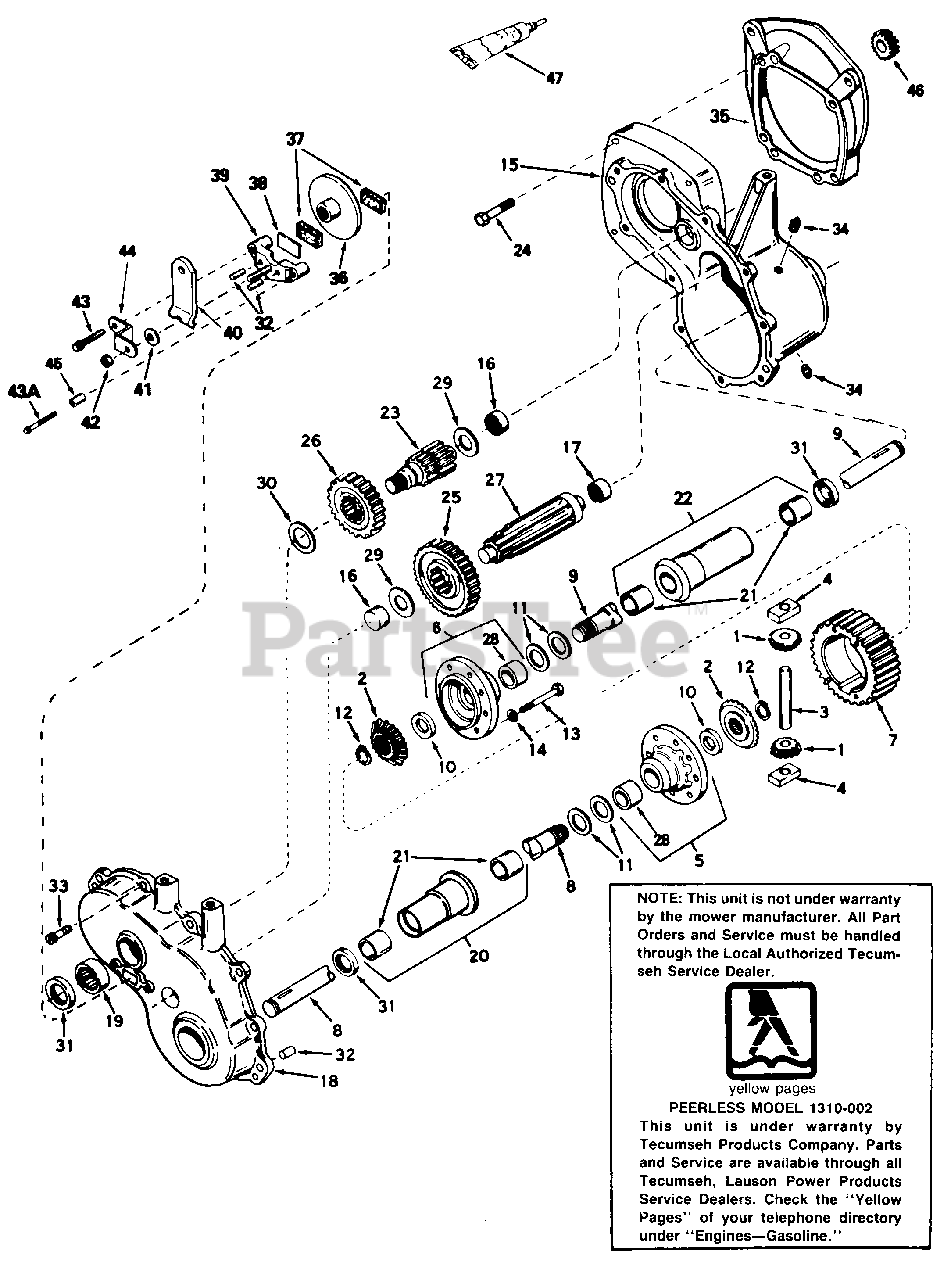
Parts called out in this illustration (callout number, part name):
1	Pinion: Bevel
2	Gear: Bevel
3	Pin: Drive
4	Block: Drive
5	Carrier Ass'y.: Differential
6	Carrier Ass'y.: Differential
7	Gear: Ring
8	Axle
9	Axle
10	Washer
11	Washer: Thrust
12	Ring: Snap
13	Screw: Hex Hd.: 1/4-20 x 21/4
14	Lock Washer: 1/4"
15	Case Ass'y.
16	Bearing: Needle
17	Bearing: Needle
18	Cover Ass'y.
19	Bearing: Needle
20	Housing & Bushing Ass'y.
21	Bushing
22	Housing & Bushing Ass'y. (12-45/64" Long)
23	Shaft: Brake
24	Screw: Hex Hd.: 3/8-16 x 2
25	Gear: Output
26	Gear: Idler
27	Shaft: Output
28	Bushing
29	Washer
30	Washer
31	Seal: Oil
32	Pin: Dowel
33	Screw: Hex Washer Hd. Thread Forming: 1/4-20 x 1
34	Plug: Pipe
35	Plate: Adapter
36	Disc: Brake
37	Pad: Brake
38	Plate: Brake Pad
39	Holder: Brake Pad
40	Lever: Brake
41	Washer: Flat
42	Lock Nut: 5/16-24
43	Screw: Flanged Hex Hd. Thread Forming: 1/4-20 x 1-1/4
43A	Screw: Flanged Hex Hd. Thread Forming: 1/4-20 x 2-1/4
44	Bracket
45	Spacer
46	Gear: Spur (18 Teeth)
47	Gasket Eliminator
